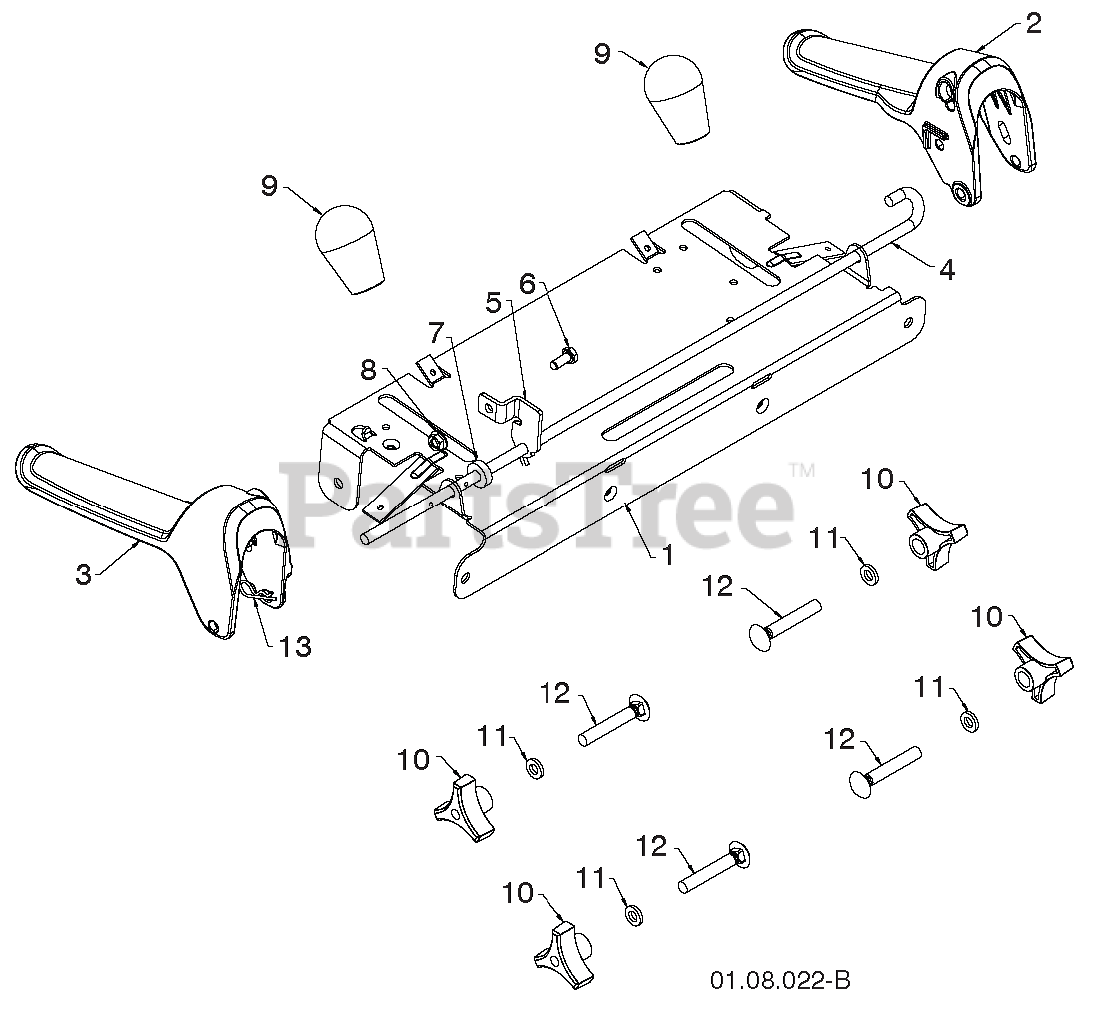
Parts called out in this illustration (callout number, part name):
1	HANDLE.LOWER.498
2	SCREW, 3/8-16X3/4
3	SUPPORT.ASM.CHUTE.ROTATOR.BLAC
4	BOLT.5/16HEX.WHS.HD
